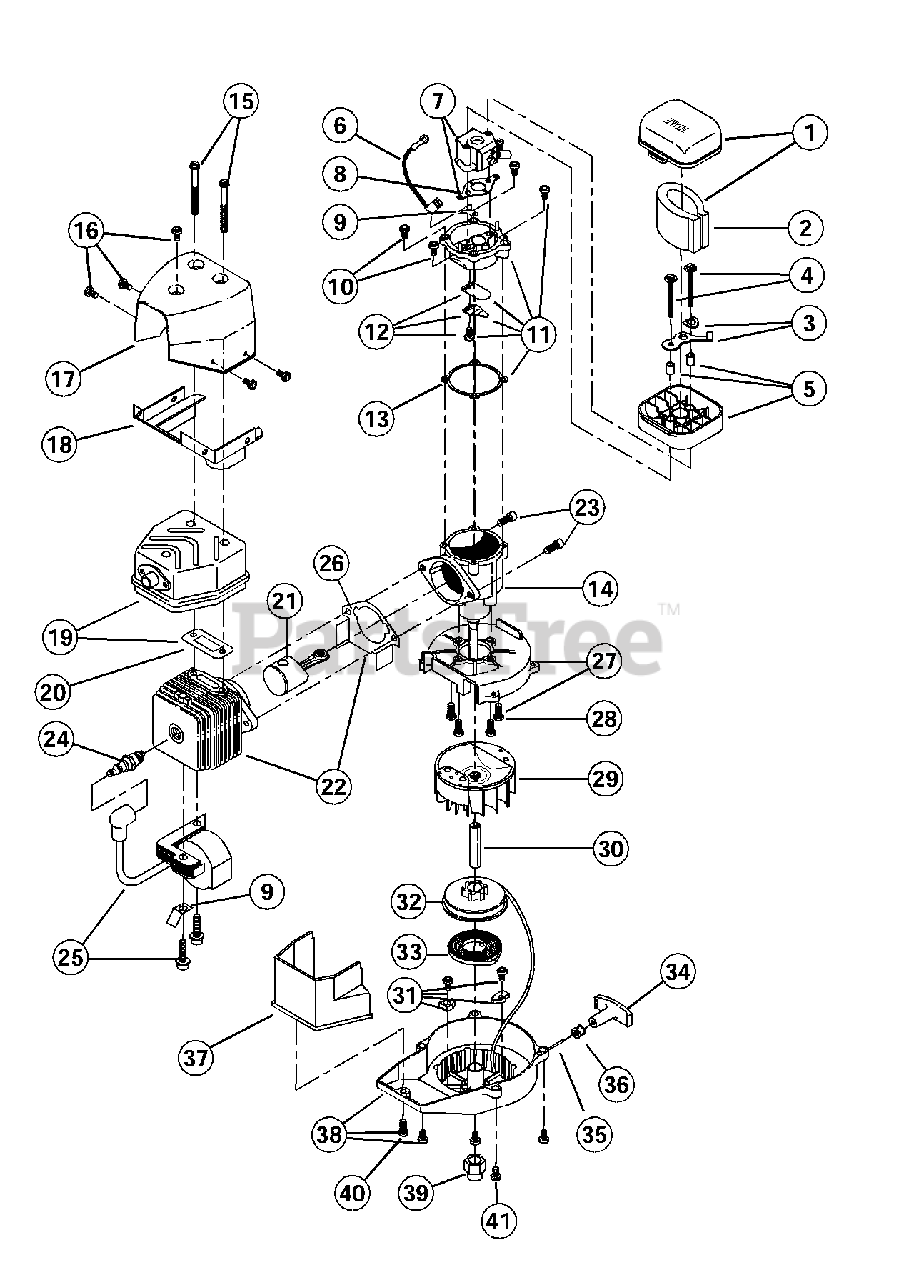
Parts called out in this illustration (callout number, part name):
1	Air Cleaner Cover Assembly
2	Air Cleaner Filter
3	Choke Lever Assembly
4	Mounting Bolt Assembly
5	Air Cleaner Base
6	Wire Lead
7	Carburetor Assembly
8	Carburetor Gasket (10 pack)
9	Ground Tab
10	Reed Plate Mounting Screw
11	Complete Reed Plate Assembly
12	Reed Assembly
13	Reed Plate Gasket
14	Crankcase Service Assembly
15	Muffler Mounting Bolt
16	Mounting Screw Assembly
17	Upper Heat Shield
18	Lower Heat Shield
19	Muffler Assembly
20	Exhaust Gasket (10 pack)
21	Piston and Rod Assembly
22	Cylinder Assembly
23	Cylinder Bolt
24	Spark Plug
25	Module Assembly
26	Cylinder Gasket
27	Shroud Assembly
28	Shroud Screw
29	Flywheel Assembly
31	Pulley Retainer Assembly
32	Recoil Pulley Assembly
33	Recoil Spring
34	Pull Handle
36	Rope Guide
37	Shroud Extension
38	Starter Housing Assembly
39	Crankshaft Extension
40	Shroud Extension Screw
41	Housing Screw
